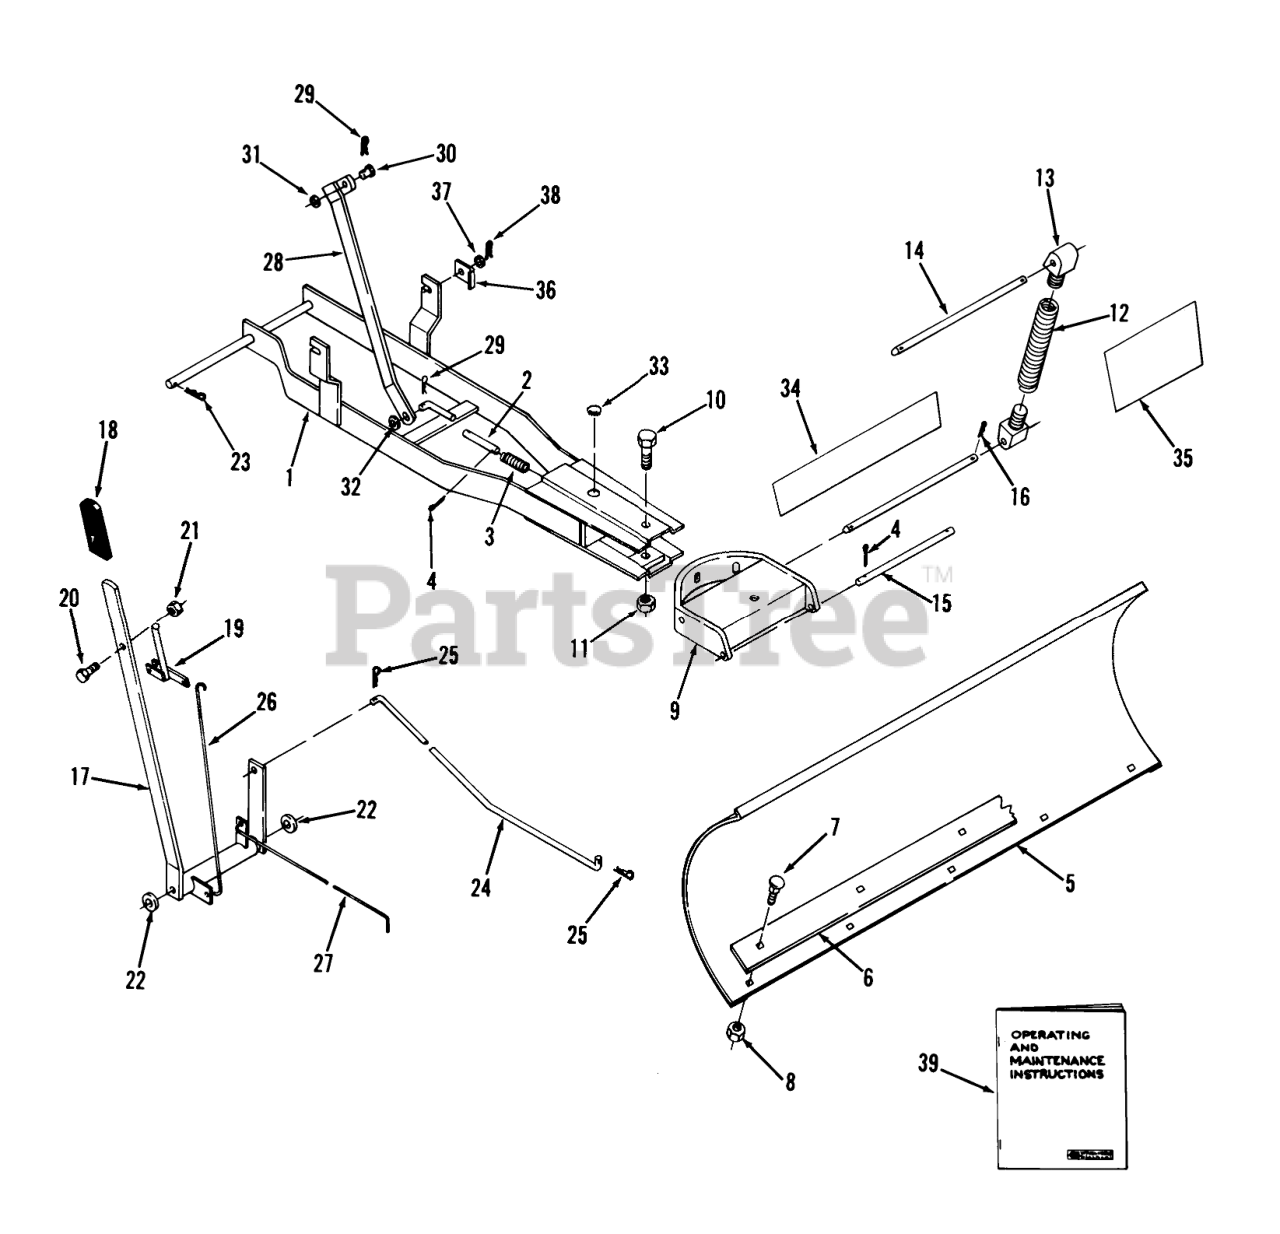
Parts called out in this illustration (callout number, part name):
1	Frame
2	Index Pin
3	SPRING-COMPRESSION
5	Blade
6	Plate
7	Bolt-Carriage
8	NUT
9	Sector and Channel
10	Bolt
11	Nut
12	Spring
13	Lug
14	ROD-PIVOT, BLADE
15	ROD-LOWER
16	Hairpin
17	Index Lever
18	GRIP
19	LEVER ASSY
20	Bolt
21	Nut
22	Washer
23	Hairpin
24	Brake Pedal
25	Hairpin
26	Upper Index Rod
27	LOWER INDEX ROD
28	Lift Bar
29	Hairpin Cotter
31	Washer
32	WASHER
33	PLUG
34	DECAL-WHEEL HORSE
35	Caution Decal
37	Washer
38	Hairpin Cotter
39	OPERATOR MANUAL
